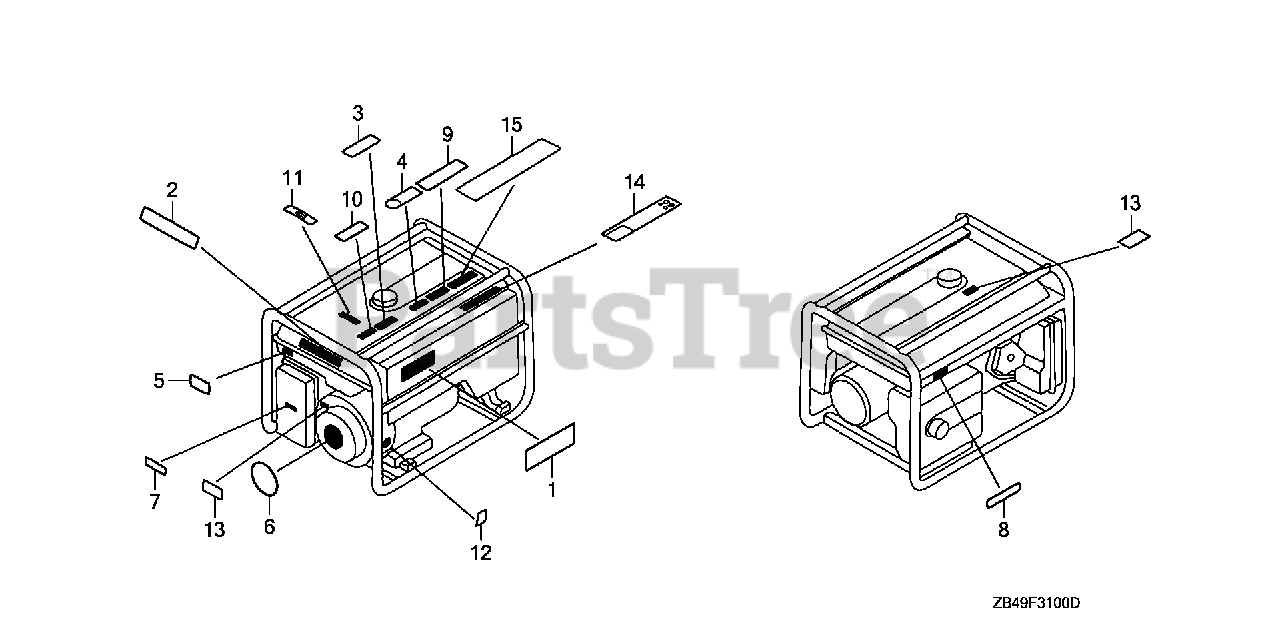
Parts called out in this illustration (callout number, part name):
1	EMBLEM (EB3500)
2	PLATE, CAUTION
3	LABEL, RAIN WARNING (ENGLISH)
4	MARK, CAUTION (ENGLISH/FRENCH/SPANISH)
5	MARK, CHOKE
7	MARK, AIR CLEANER (ENGLISH)
8	MARK, EX. CAUTION (ENGLISH/FRENCH)
9	MARK, CAUTION (ENGLISH/FRENCH/SPANISH)
10	LABEL, CONNECT WARNING (ENGLISH)
11	PLATE, FUEL INDICATION
12	MARK, OIL CAUTION
13	LABEL, FUEL CAUTION
14	MARK, WARNING (GFCI)
